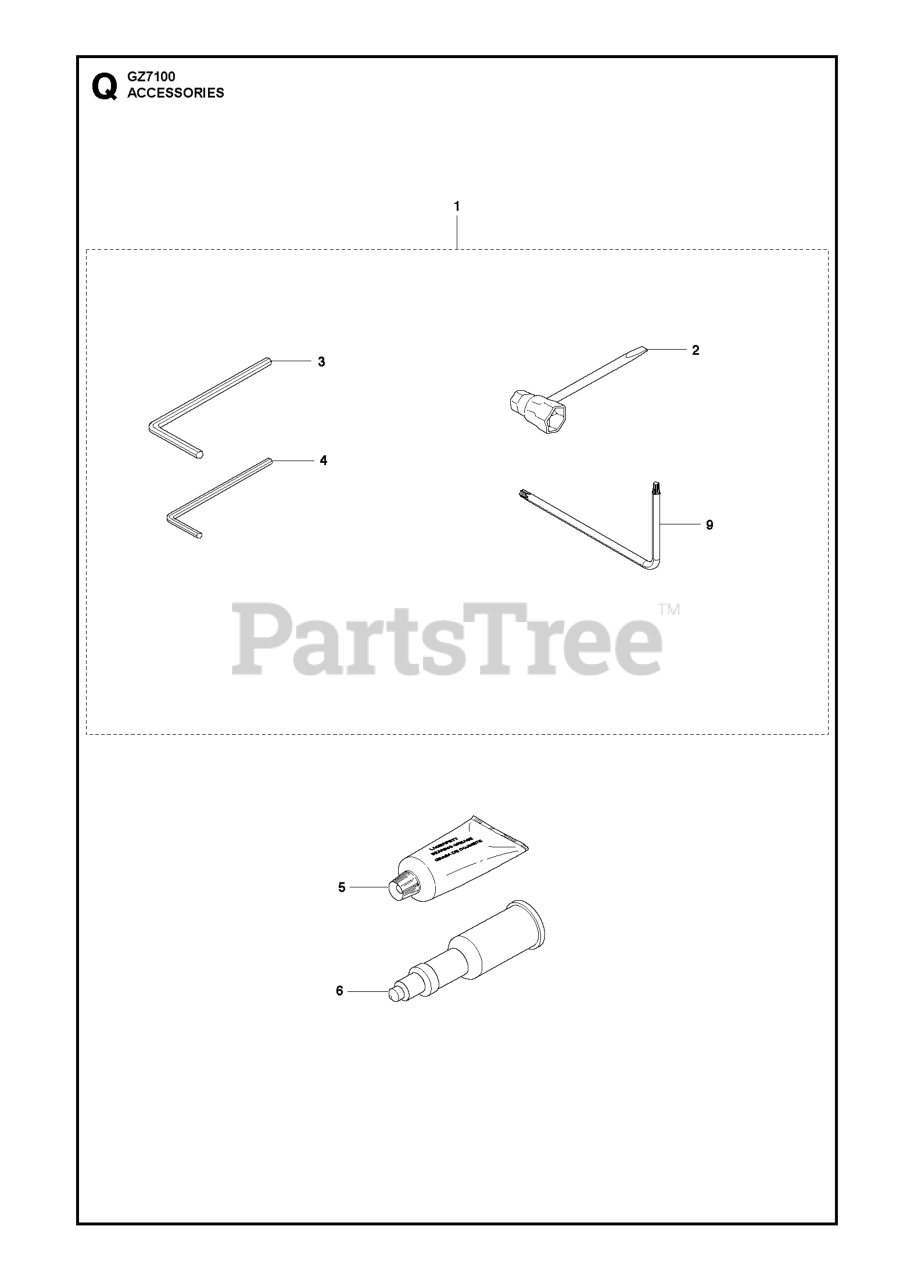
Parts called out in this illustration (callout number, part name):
1	TOOL KIT
2	COMBI TOOL
3	L-SPANNER
4	L-SPANNER
6	GREASE GUN
9	WRENCH
